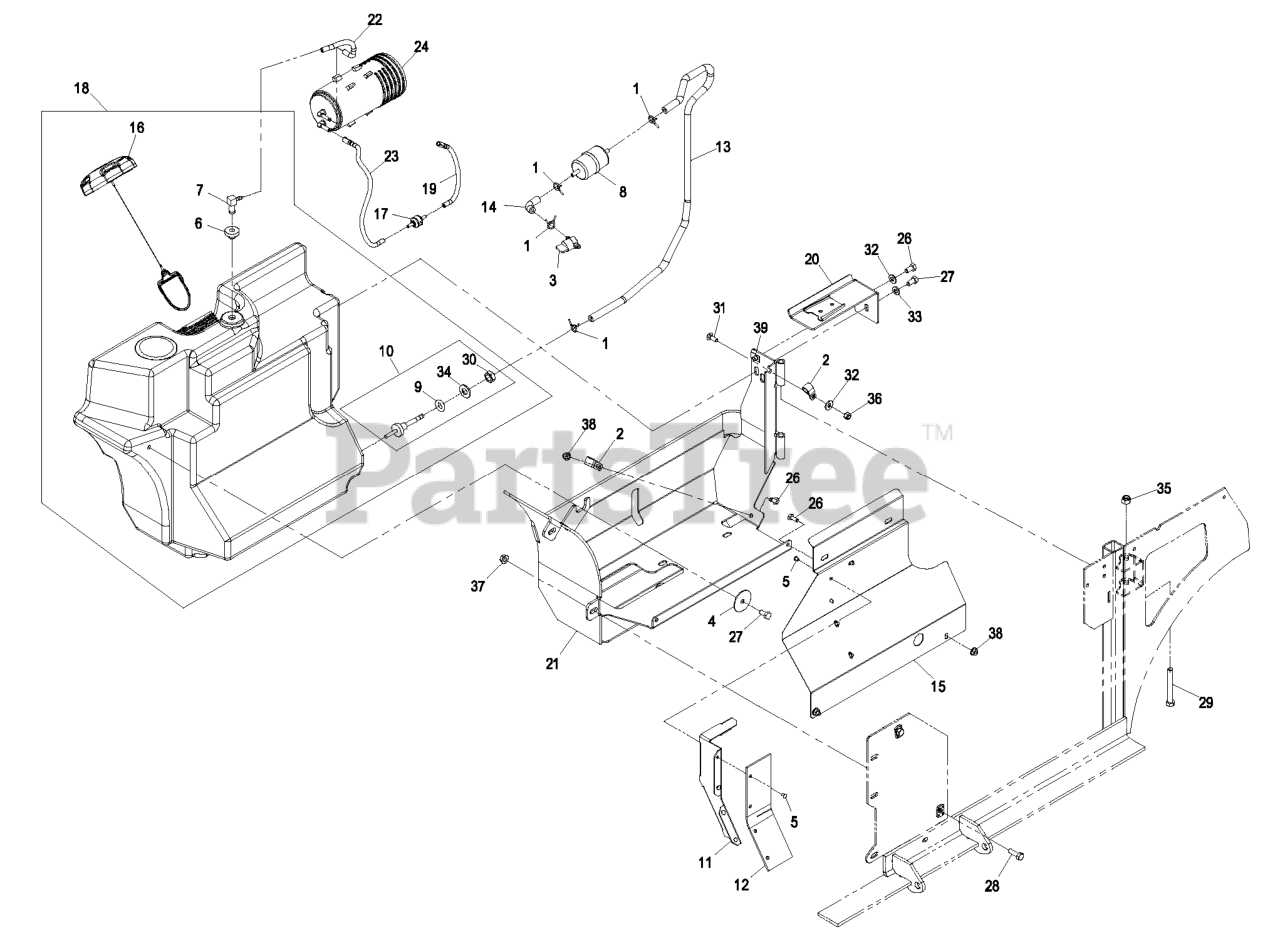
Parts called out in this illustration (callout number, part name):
2	CLIP-LOOM
3	VALVE-FUEL
5	RIVET-POP
6	BUSHING
8	Part No. 2405010 Fuel Filter
9	O-RING,BULKHEAD FITTING
10	FITTING-FUEL, BULKHEAD
11	Deflector, Air
12	FLAP-RUBBER
13	HOSE-FUEL
14	HOSE-FUEL
15	Panel, Tank Shield
19	HOSE-VENT, FORMED
21	Asm, Tank Frame
22	HOSE-VENT, FORMED
23	HOSE-VENT, FORMED
24	CANISTER-CARBON, 800CC
26	SCREW-HH
27	SCREW-HH
28	SCREW-HH
29	SCREW-CARR
30	NUT-JAM
31	BOLT-CARR
32	WASHER-FLAT
33	WASHER-PLAIN
34	WASHER-FLAT
35	NUT-LOCK, NI
36	NUT-LOCK, NI
39	Nut, Retainer-Panel 1/4-20
